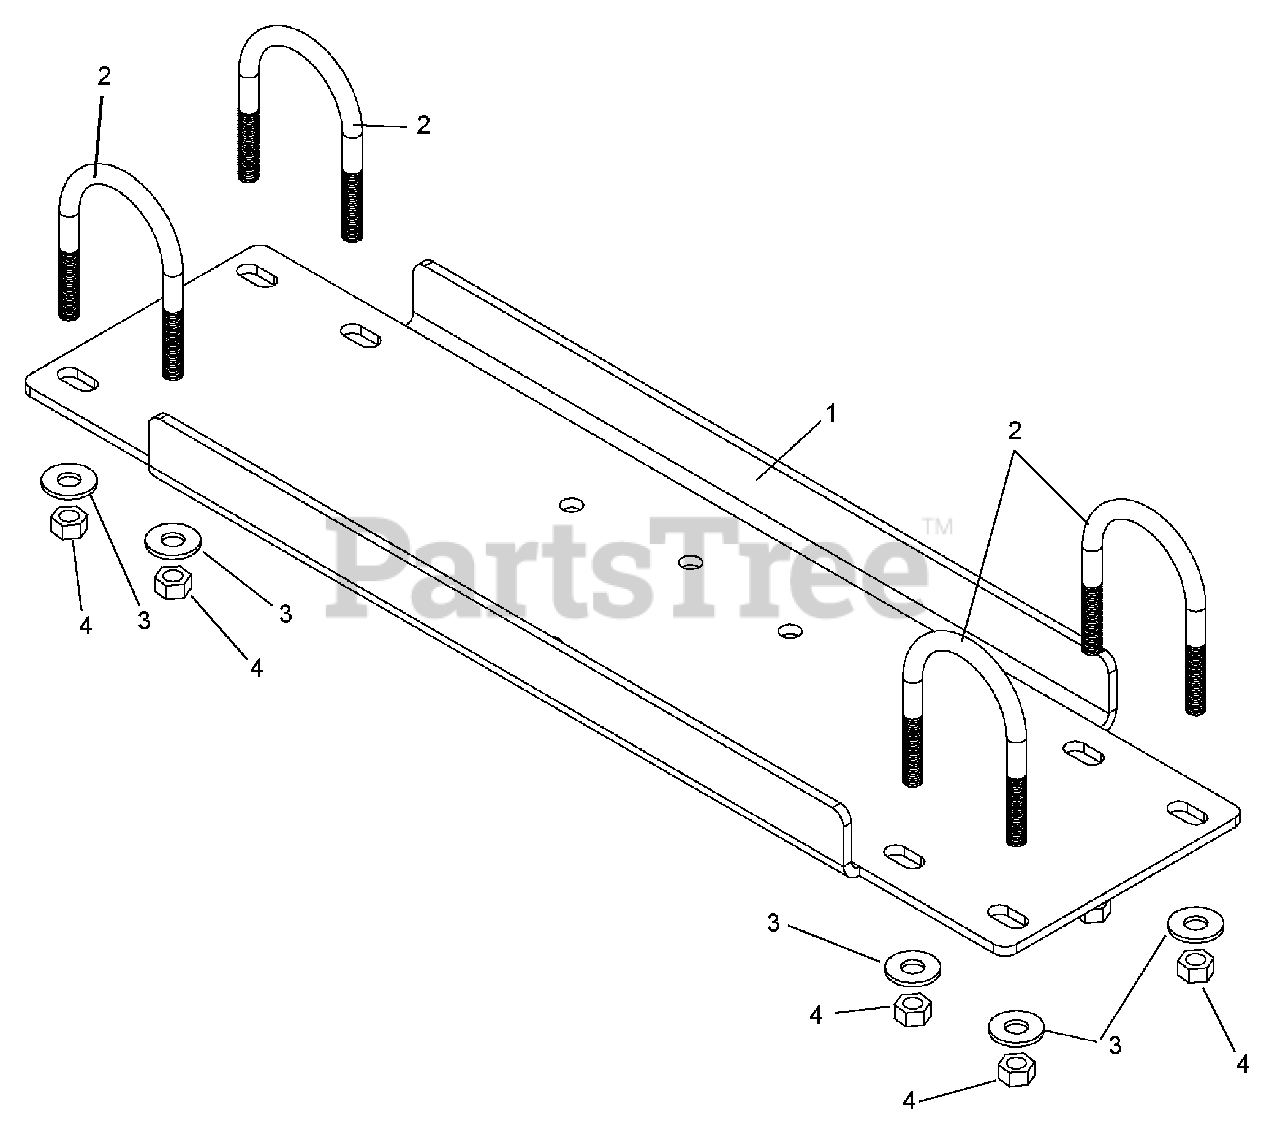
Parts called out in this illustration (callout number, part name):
1	NT Series Winch Mount Plate
2	5/16" x 2" x 3 U-Bolt
3	5/16" Flat Washer
4	5/16" Nylock Nut
